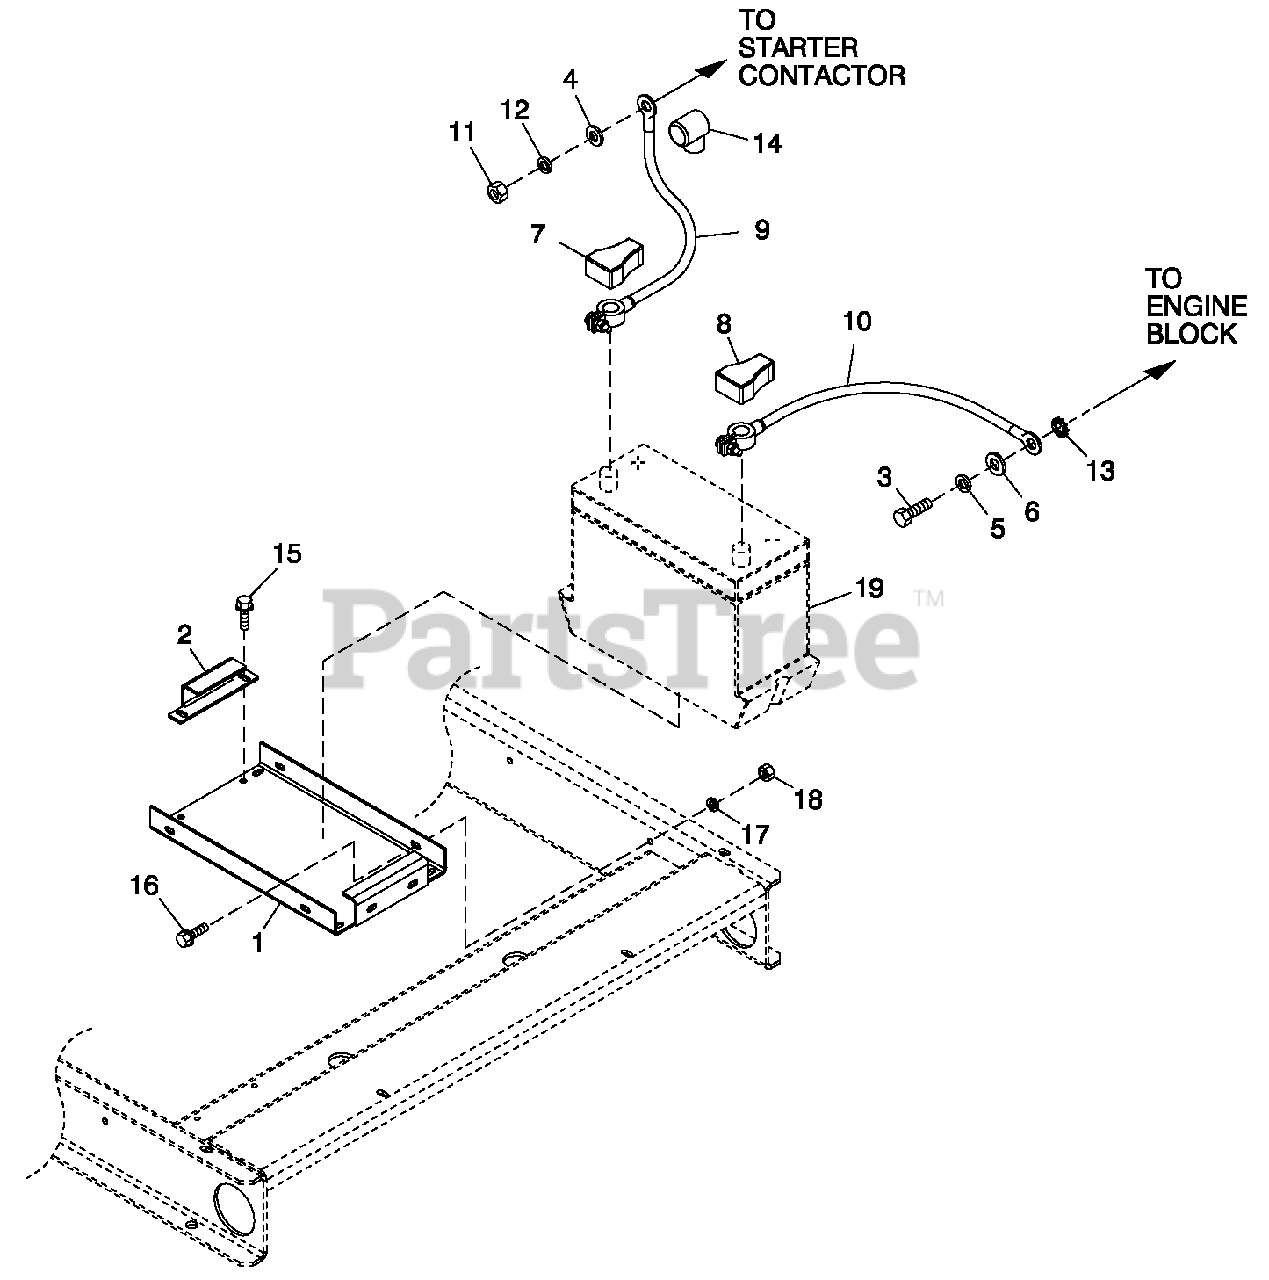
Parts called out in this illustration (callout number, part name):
1	TRAY BATTERY
2	STRAP BATTERY RETAINMENT
3	SCREW HHC M12-1.75 X 25 G8.8
4	WASHER FLAT 5/16-M8 ZINC
5	WASHER LOCK 1/2
6	WASHER FLAT 1/2 ZINC
7	BATTERY POST COVER RED +
8	BATTERY POST COVER BLACK -
9	CABLE BATT RED #1X28.00
10	CABLE BATT BLK #1 X 30.00 NEG
11	NUTHEXM8-1.25 G8 YEL CHR
12	WASHER LOCK M8-5/16
13	WASHER SHAKEPROOF EXT 7/16 STL
14	BOOT CONTACTOR CABLES
15	SCREW THF M6-1 X 16 N WA Z/JS
16	SCREW HHC M6-1.0X 20 G8.8
17	WASHER LOCK M6-1/4
18	NUT HEX M6 X 1.0 G8 YEL CHR
19	BATT 12VDC 24F 525 CCA (SOLD AS AN OPTION)
